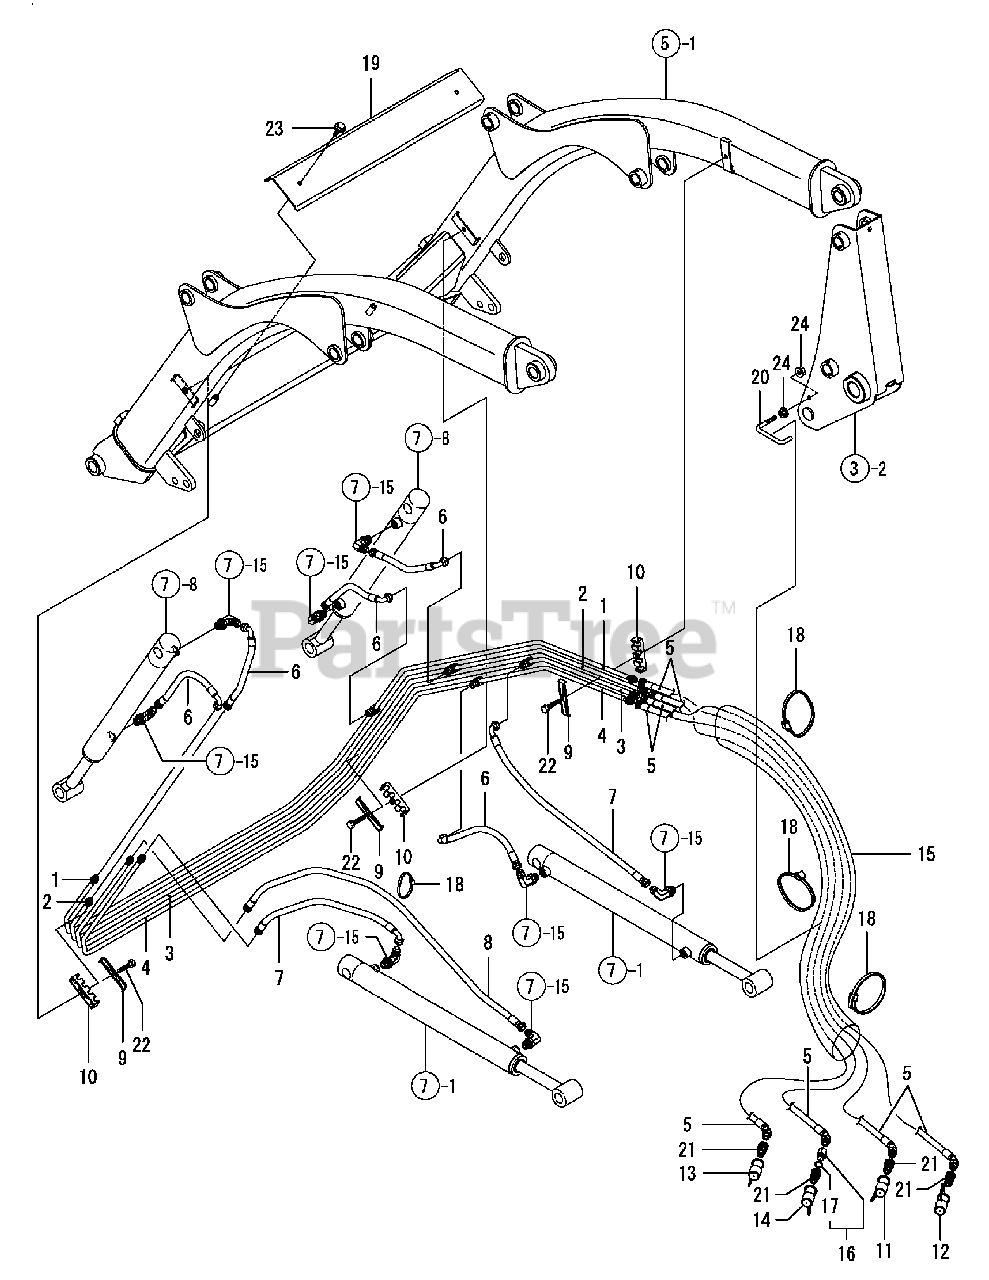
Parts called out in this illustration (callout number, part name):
5	HP Hose, Intake
11	Dust Plug, Red M
12	Dust Plug, Blue M
13	Dust Plug, Yellow M
14	Dust Plug, Green M
15	Cover, Hose Intake
16	Orfice Assy, 1/8
21	Coupler,Quick 1/4M
22	Bolt M 6X 30 Plated
23	Bolt M 8X 16 Plated
